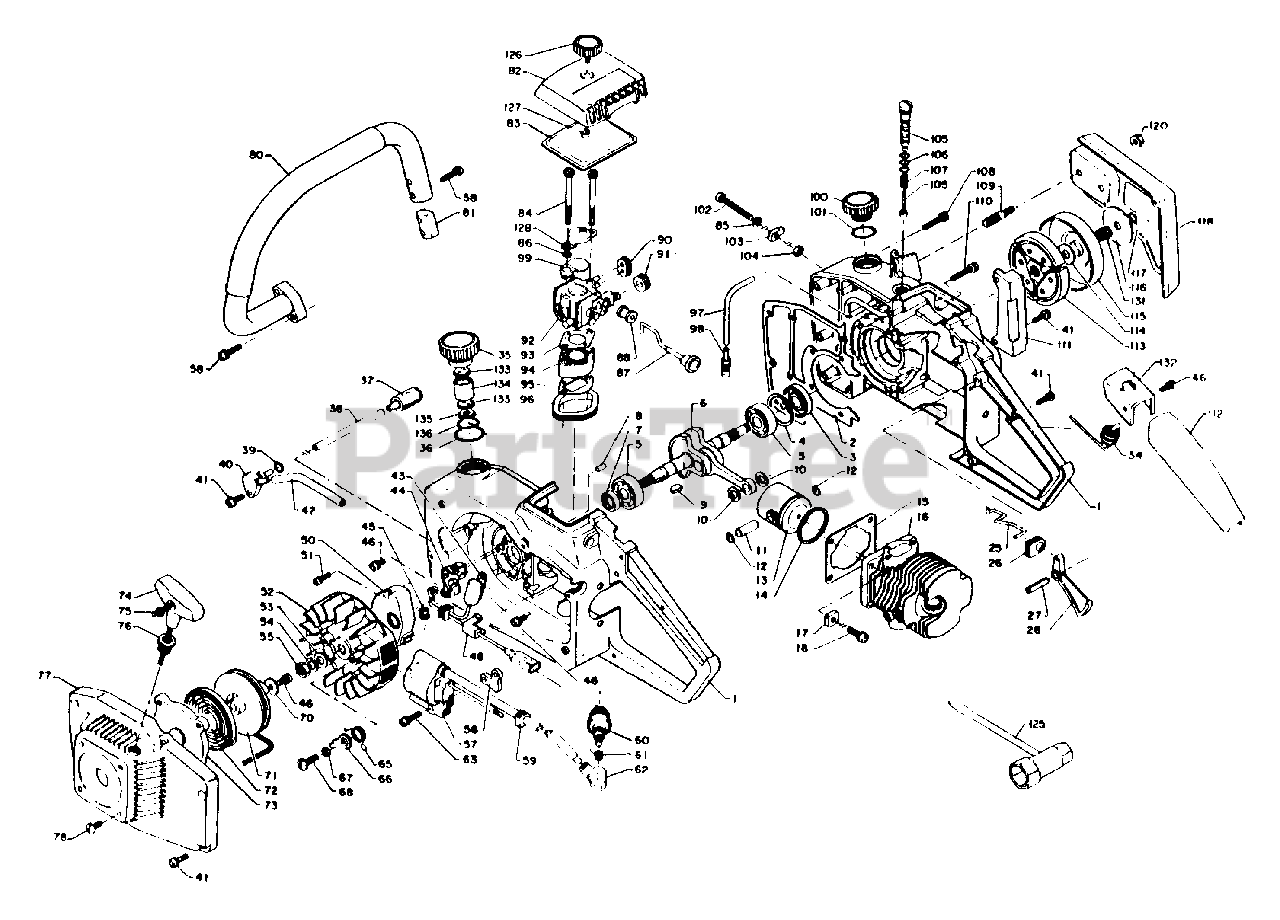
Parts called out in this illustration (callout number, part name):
1	CRANKCASE KIT
2	GASKET, CRANKCASE
3	SEAL, OIL
4	RING, SNAP Ø32
5	BEARING, BALL - 6201 C3
6	CRANKSHAFT ASSY
7	SEAL, OIL
8	PIN, LOCATING 4
10	SPACER, PISTON
11	PIN, PISTON
12	RING, SNAP
13	PISTON
14	RING, PISTON
15	GASKET, CYLINDER
16	CYLINDER
17	NUT
18	SCREW 5×22
25	ROD, THROTTLE
26	RUBBER GROMMET-THROTTLE
27	PIN, SPRING 5×25
28	TRIGGER, THROTTLE
34	IGNITION SWITCH ASSY
35	CAP ASSY
36	O-RING 22
37	FILTER, FUEL
38	PIPE, FUEL - INNER
39	O-RING 7 MM
40	CONNECTOR, PIPE
41	SCREW 4×14
42	PIPE, FUEL - OUTER
43	CONDENSER
44	CONTACT POINT SET
45	PAD, OIL
46	SCREW 4×10
48	CLAMP
50	COVER, BREAKER
51	SCREW - 3×16
52	FLYWHEEL
53	WASHER 8.5×16×1.2
54	WASHER, SPRING 8
55	NUT 8×1.25
56	SPACER
57	COIL, IGNITION
58	SCREW 4×20
59	BUSHING
60	SPARK PLUG - BM6A
61	TERMINAL, SPARK PLUG CAP
62	CAP, SPARK PLUG
65	SPRING
66	PAWL, STARTER
67	SPACER 5.2×8×2.1
68	SCREW
70	WASHER 4.2×16.5×1
71	REEL, ROPE
72	SPRING, REWIND
73	CASE, STARTER
75	ROPE, STARTER 3.5×850
76	GUIDE, ROPE
77	CASE, STARTER
78	SCREW
80	HANDLE, FRONT
81	INSERT
82	COVER, AIR FILTER
83	FILTER, AIR
84	BOLT 5×55
85	WASHER, FLAT 5.5×10×0.8
86	WASHER 5.2×8×0.8T
87	ROD, CHOKE
88	GROMMET, CHOKE
92	CARBURETOR
93	GASKET, INTAKE
94	INSULATOR, INTAKE
95	GASKET, INTAKE
96	GROMMET-INTAKE
97	PIPE, OIL
98	FILTER, OIL
99	SHUTTER, CHOKE
100	CAP, OIL TANK
101	O-RING 16 MM
102	SCREW 5×40
103	TENSIONER
104	LOCKNUT - 5
105	AUTO-OILER ASSY
108	SCREW 4×25
109	STUD, GUIDE BAR
110	SCREW - 4×25
111	SEAL, DUST
112	GRIP, REAR HANDLE
113	CLUTCH ASSY
114	WASHER, CLUTCH
115	CASE, CLUTCH
116	WASHER, CLUTCH
117	RING, SNAP
118	GUARD, SPROCKET
120	NUT - FLANGE
125	T-WRENCH 10×19 MM
126	THUMBSCREW
127	E-RING 3
128	BRACKET, AIR FILTER
131	BEARING, NEEDLE 8
132	BRACKET, SWITCH
133	SPACER
135	FILTER, FUEL
136	RING, RETAINING
